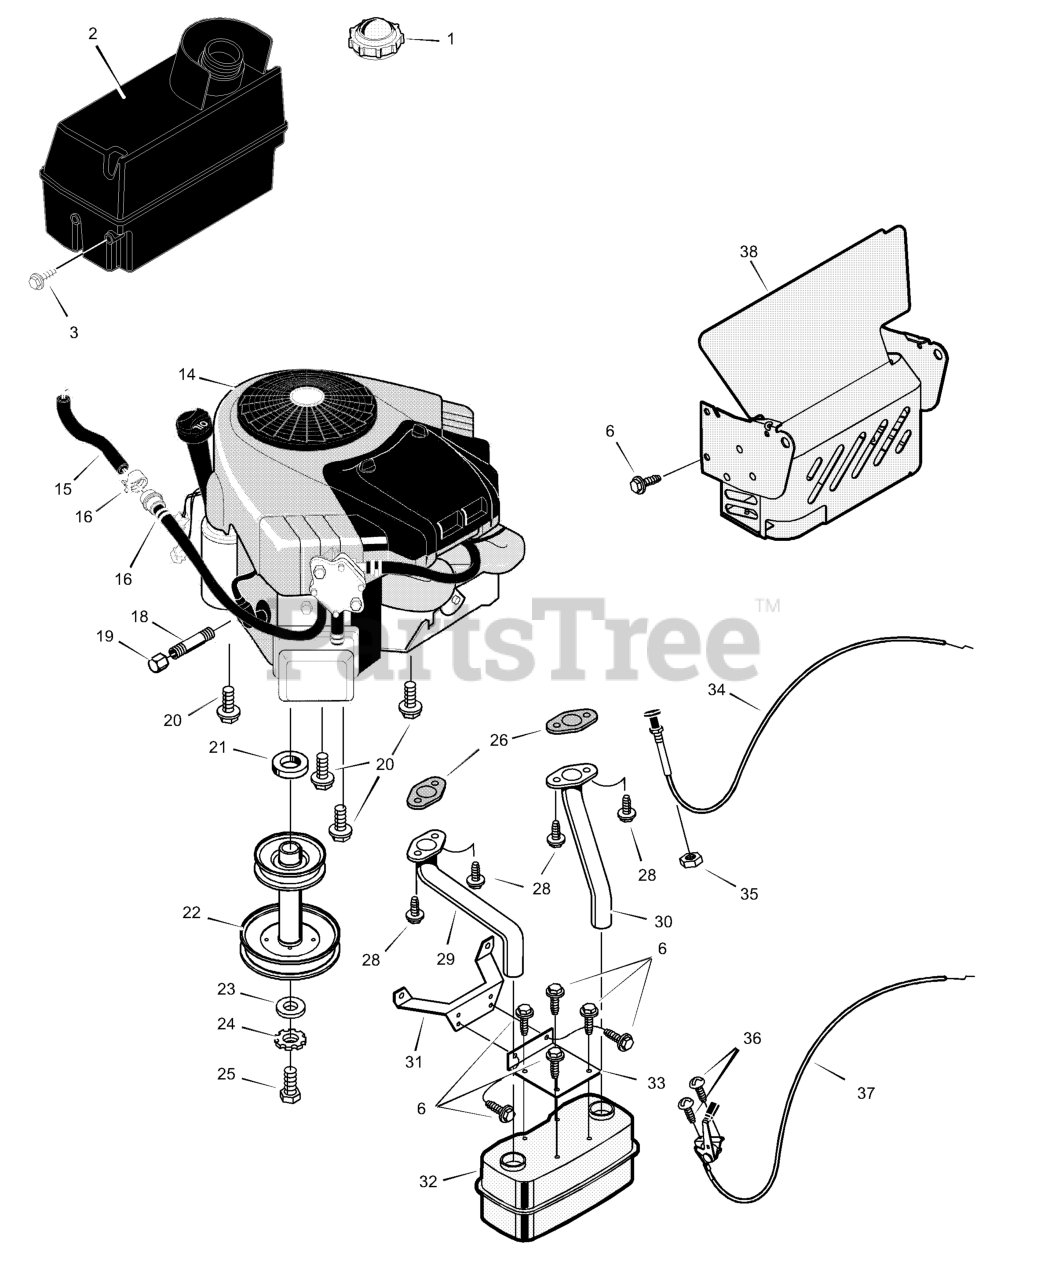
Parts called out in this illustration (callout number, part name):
1	Cap, Fuel *
2	Tank, Fuel
14	Engine
15	Fuel Line (Must cut to length) *
16	Clamp *
18	Pipe, Oil Drain
19	Cap, Oil Drain
20	Bolt
22	Pulley, Stack
24	Lockwasher
27	Washer
29	Tube, Right Exhaust
30	Tube, Left Exhaust
31	Bracket, Muffler Mount
32	Muffler
33	Bracket, Muffler
35	Nut
37	Control, Throttle
38	Shield Assembly, Heat
